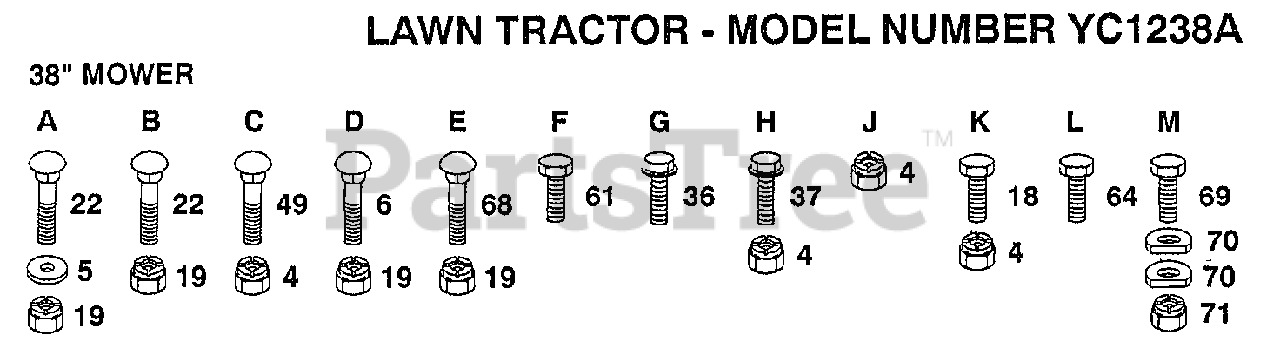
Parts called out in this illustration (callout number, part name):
5	WASHER M
6	BOLT
22	BOLT
36	SCREW
37	SCREW
49	BOLT
61	BOLT
64	BOLT.3/8-14X1.25
69	BOLT LT
70	WASHER T
